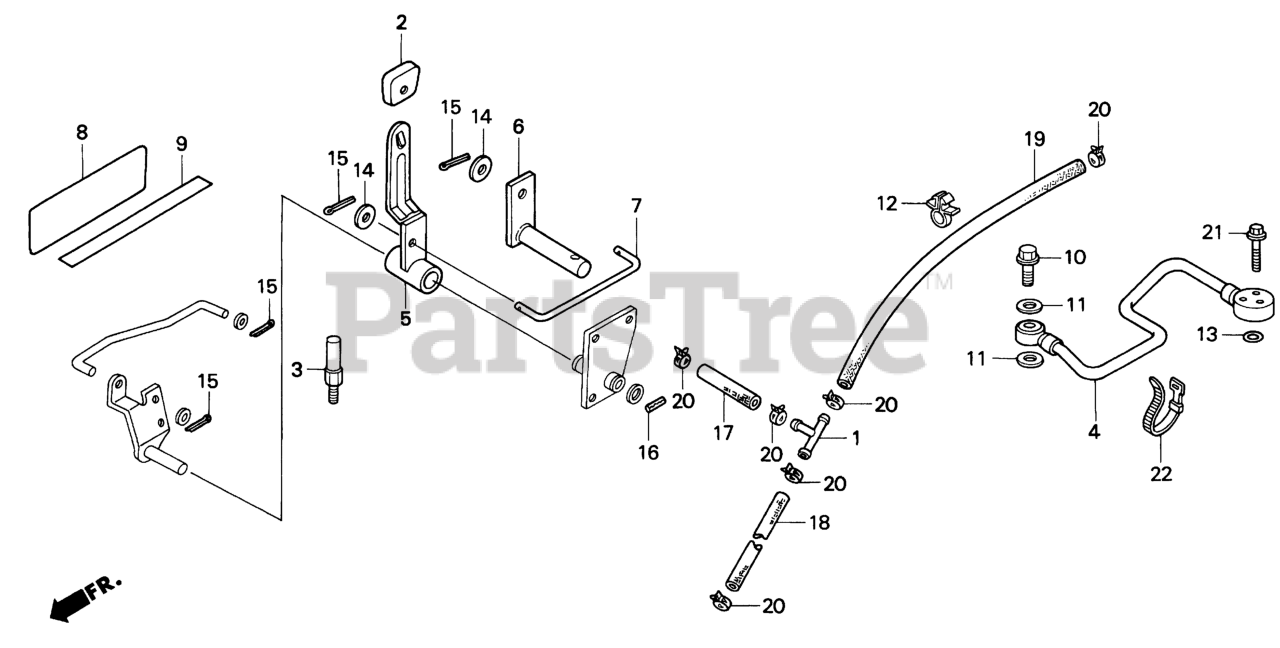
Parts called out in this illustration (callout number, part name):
1	JOINT, BREATHER THREE WAY
2	GRIP, ADJUSTER
3	BOLT, STOPPER
4	PIPE, FEED (B)
5	LEVER, ROTARY VALVE
6	ARM, ROTARY VALVE
7	JOINT, ROTARY VALVE
8	LABEL, HYDRAULIC ADJUST
9	MARK, HYDRAULIC CHANGE
10	BOLT A, JOINT
11	WASHER, JOINT (14MM)
12	CLIP, WIRE HARNESS
13	O-RING (11.8X1.9)
14	WASHER, PLAIN (8MM)
15	PIN, COTTER (2.5MM)
16	PIN, SPRING (4X20)
17	BULK HOSE, FUEL (7.5X3000) (7.3X150)
18	BULK HOSE, FUEL (7.5X3000) (7.3X150)
19	BULK HOSE, FUEL (7.5X3000) (7.3X150)
20	CLIP, TUBE (D12.5)
21	BOLT, FLANGE (6X35)
22	BAND, CABLE (120MM) (BLACK)
